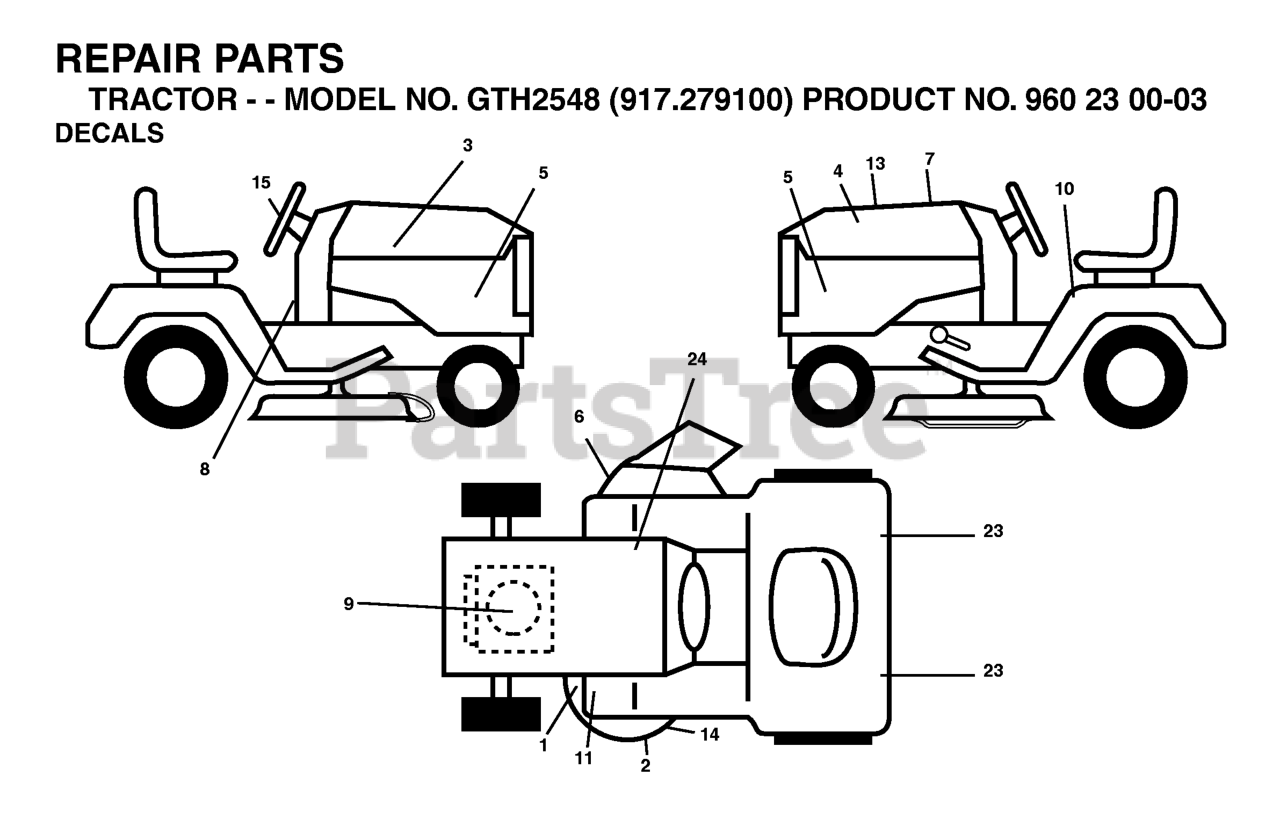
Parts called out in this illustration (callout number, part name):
1	DECAL CLUTCH/BRAKE
5	DECAL, GTH2548
6	DECAL.WARN.KEEP.HAND.AWAY
7	DECAL HOOD CUST. RESP.
8	DECAL.SADDLE.OPERATOR
10	DECAL FENDER DANGER
11	DECAL, FOOTREST
13	DECAL, GTH2548
14	DECAL V-BELT SCHEMATIC
15	DECAL.STEERING.HUSQ.BLUE
23	REFLECTOR-TAIL YT
24	DECAL BTRY SYMBOLS
